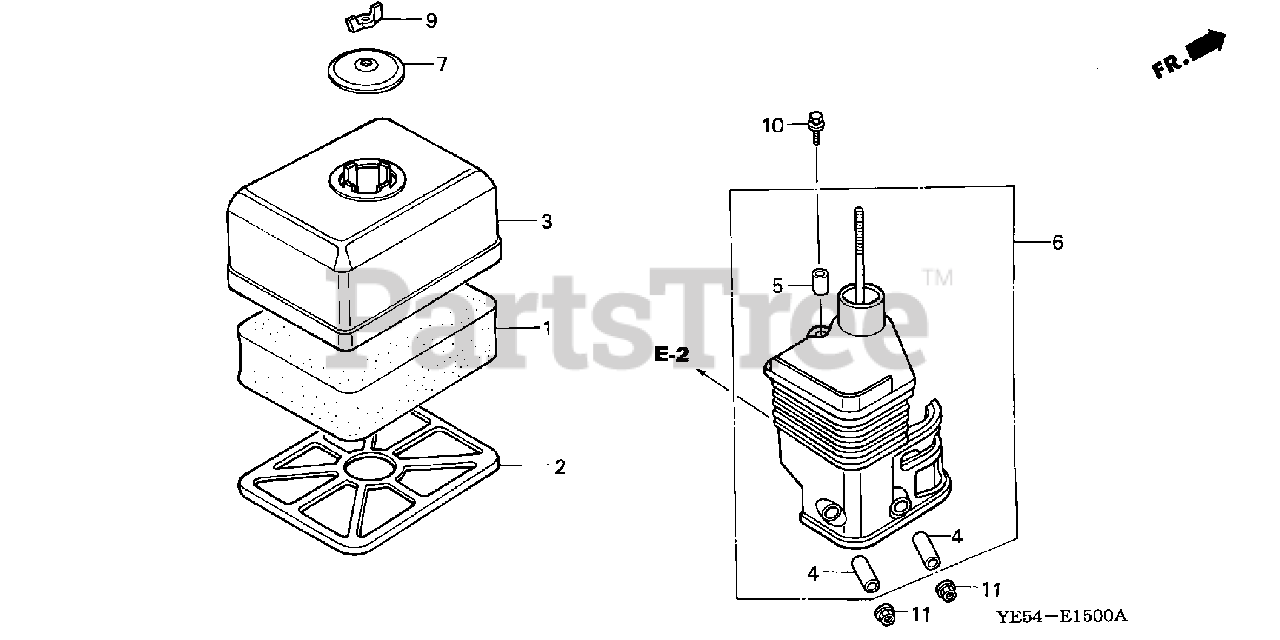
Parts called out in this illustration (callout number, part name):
1	ELEMENT, AIR CLEANER (SEMI-DRY)
2	GRID, AIR CLEANER (SEMI-DRY)
3	COVER, AIR CLEANER (SEMI-DRY)
4	COLLAR, AIR CLEANER
5	COLLAR B, AIR CLEANER
6	ELBOW, AIR CLEANER
7	CAP, CLEANER
9	WINGNUT, TOOL BOX SETTING
10	BOLT, FLANGE (6X20)
11	NUT, FLANGE (6MM)
